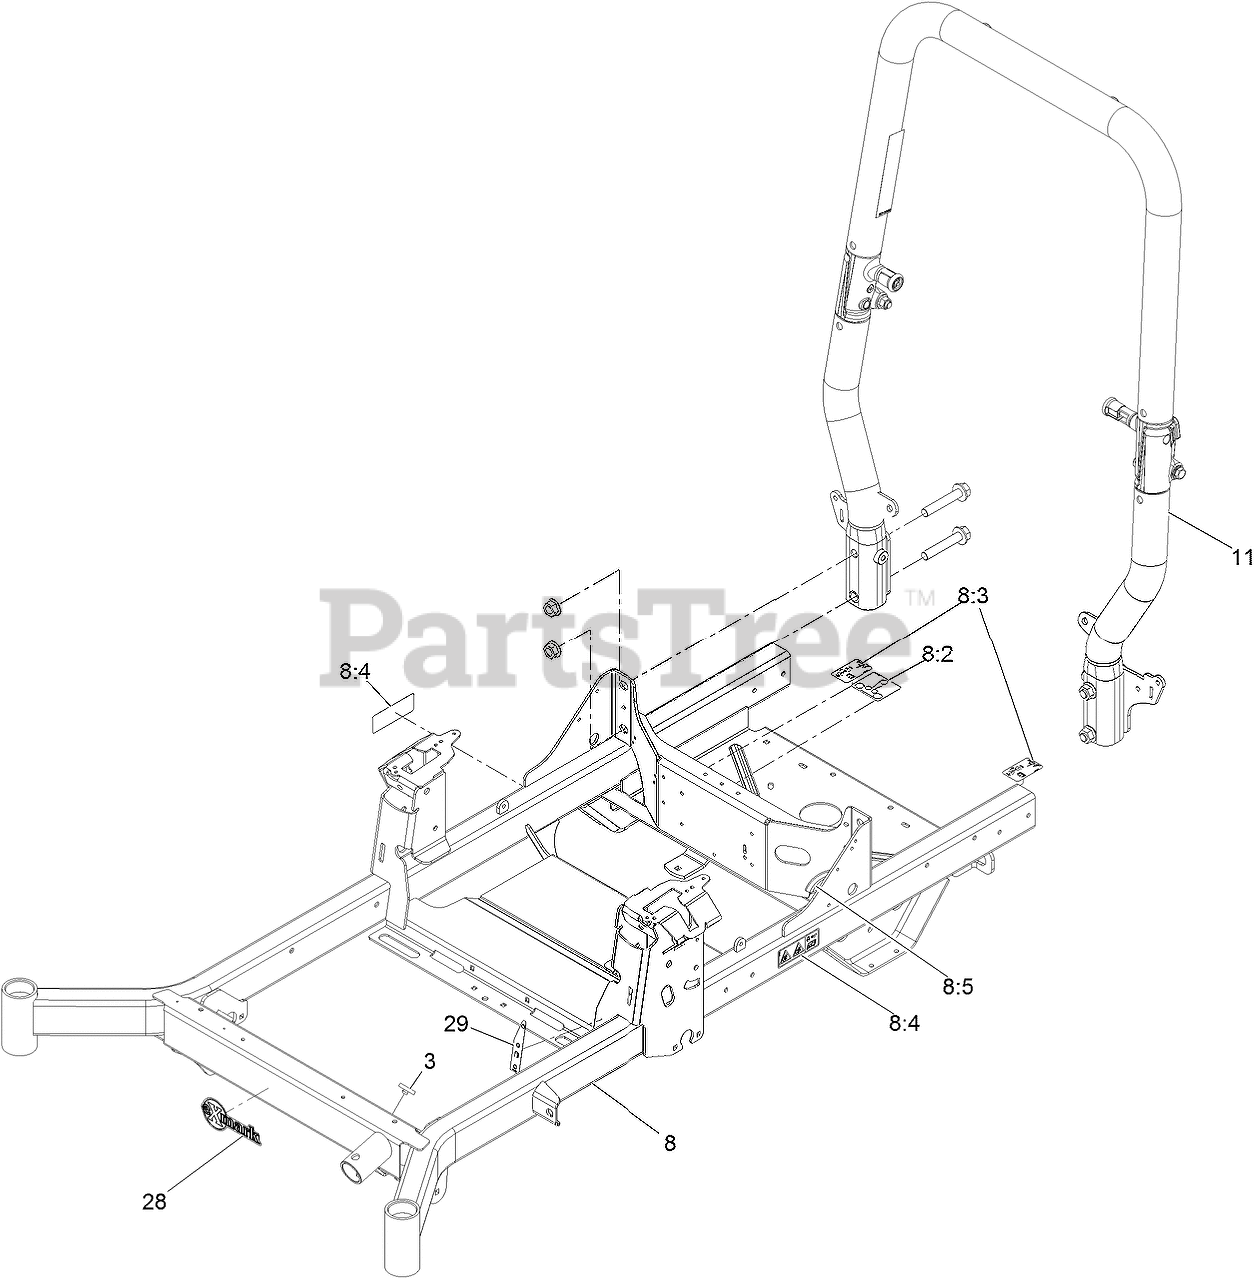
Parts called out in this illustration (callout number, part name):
3	BUMPER-PUSH-IN, RUBBER
8	Frame-60Rd,Suspension
8:2	DECAL-ROUTING, BELT
8:3	DECAL-RELEASE, DRIVE
8:4	DECAL-WARNING
8:5	STRIP-SEAL
11	ASM-ROPS TAPERED
28	DECAL-EXMARK LOGO
29	DECAL-FILL, FUEL
